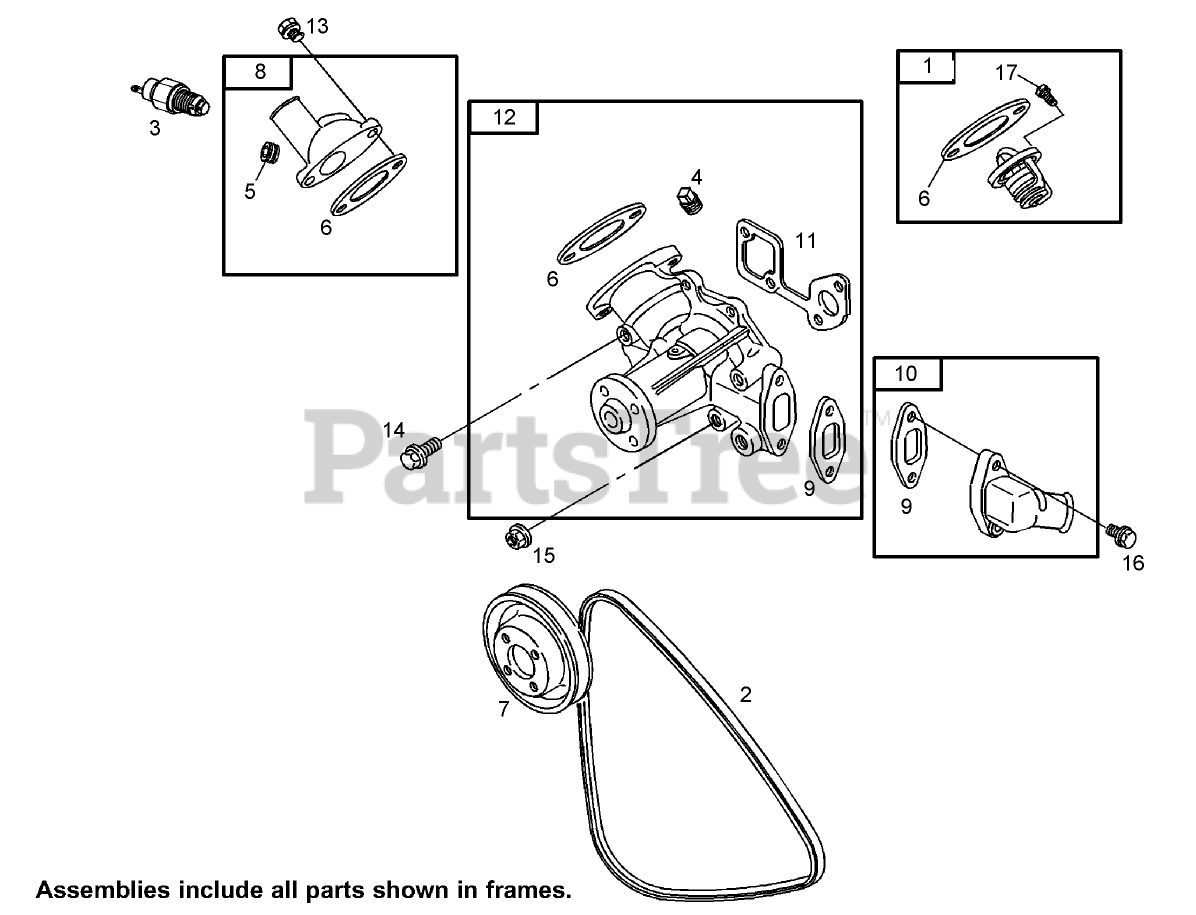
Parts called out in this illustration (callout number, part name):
1	THERMOSTAT
2	BELT-V
3	SWITCH-TEMPERATURE, WATER
6	GASKET-OUTLET
7	PULLEY-PUMP
8	HOUSING-OUTLET
9	GASKET-HOUSING, INLET
10	HOUSING-INLET
11	GASKET-PUMP, WATER
12	PUMP-WATER
13	SCREW-HEX
14	SCREW-HEX
15	NUT-HEX, METRIC
16	SCREW-HEX
17	SCREW-METRIC
